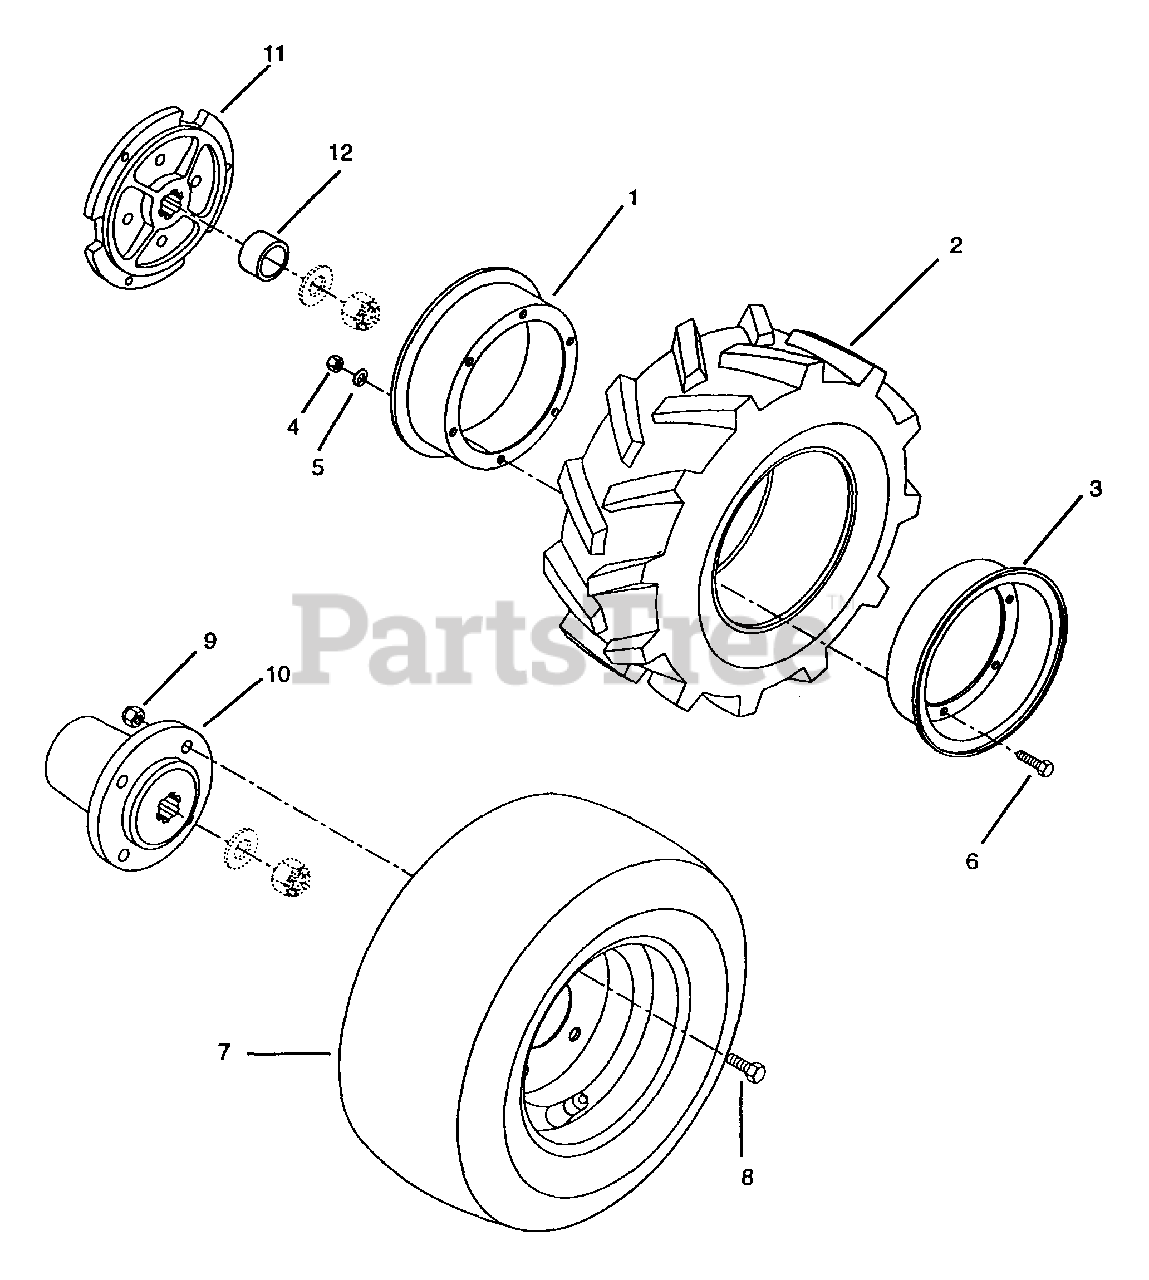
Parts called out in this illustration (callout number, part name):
1	Wheel 7.71 x 1.25
2	Tire 16 x 5W x 3
3	Wheel-Disc 6.75 x 9.219
4	Nut-Jam .375-16
5	Washer-Lock.375 x.094
6	Bolt-Hex .36-16 x .625
7	Tire/Wheel Assembly 8.50-8 x 18
8	Bolt-Hex .50-13 x 1.50 Grade 5
9	Nut-Locking-Nylon.50-13 Grade 5
10	Hub, 7" Wheel
11	Hub, Wheel
12	Bushing, Sleeve 1.02 x 1.37 x 1.13
